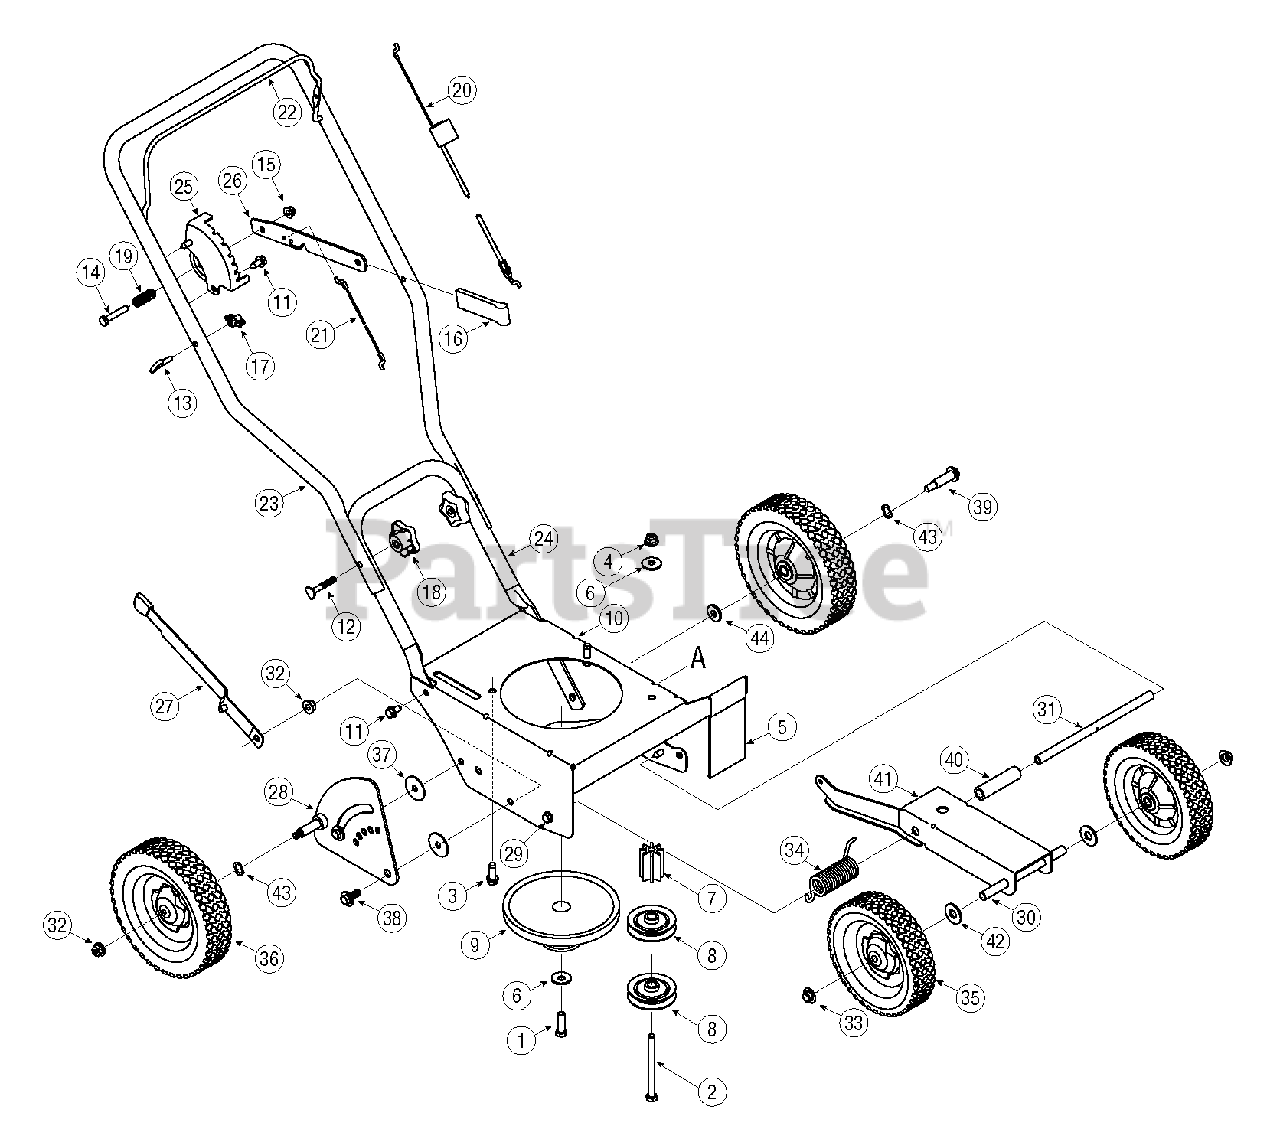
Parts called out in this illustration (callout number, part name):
1	Screw 3/8-24
2	Screw 3/8-16
3	Screw, 3/8-16
4	Flange Lock Nut, 3/8-16
5	Debris Guard
6	Bell Washer,.396 x 1.140
7	Pulley Mount Spacer
8	Flat Idler Pulley, 2.5 OD
9	Combination Flywheel
12	Carriage Bolt, 5/16-18
13	Rope Guide (Eye Bolt)
14	Hex Screw, 5/16-18
15	Lock Flange Nut, 5/16-18
18	Hand Knob
19	Compression Spring
20	Control Cable (Briggs & Stratton)
21	Wheel Adjustment Cable
24	Threaded Frame Spacer
27	Curb Height Adjustment
28	Curb Height Adjuster Plate
29	Hex Screw 5/16-18x.625x12
30	Axle Shaft .50x6.65
31	Frame Spacer .50x9.25
32	Flange Nut 3/8-16
33	Push Cap 1/2" rod
34	Torsion Spring
35	Wheel 7x1.8
36	Wheel 8x1.8
37	Flat Washer, .385 x 1.5 x .075
38	Shoulder Screw, 3/8-16
39	Shoulder Screw, 3/8-16
42	Flat Washer 1/2 x 1.25 x .10
43	Wave Washer .531 x .781 x .013
44	Flat Washer .385 x 1.0 x .135
